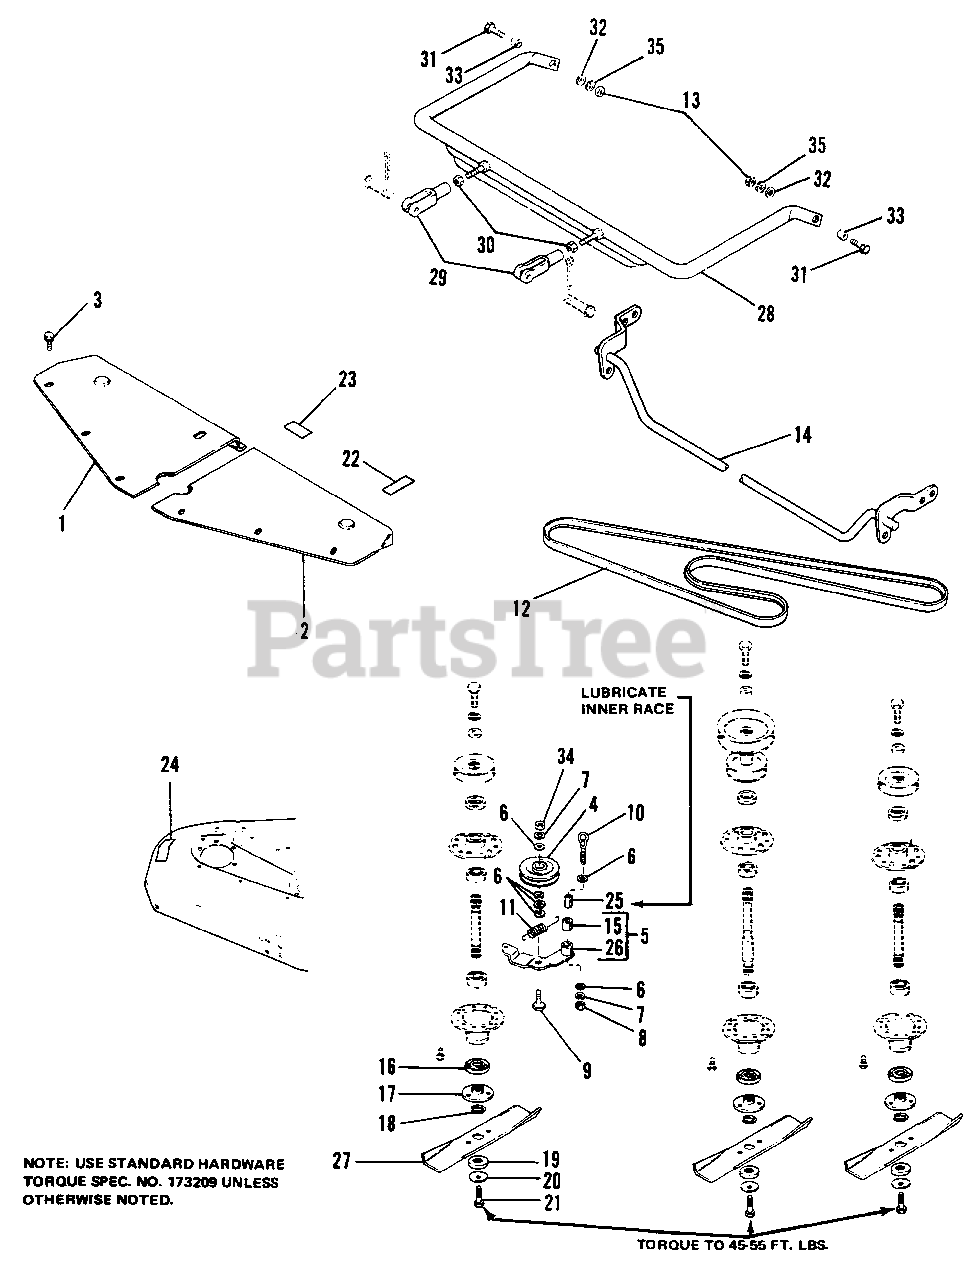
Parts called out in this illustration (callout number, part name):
1	COVER, R.H.
2	COVER, L.H.
3	SCREW, Hex, Taptite, 1/4-20 x 3/8
4	PULLEY, Idler
5	LEVER ASSY, Idler (w/Bushings)
6	WASHER, Plain, 5/16
7	LOCKWASHER, 3/8
8	NUT, Hex, Full, 3/8-16
9	CAPSCREW, Hex Hd., 3/8-16 x 1-1/4
12	BELT, V, Arbor Drive
13	NUT, Hex, Full, 1/2-13
14	ROCKER ARM ASSY
16	SHIELD, Grass
17	ADAPTOR, Blade
18	RING, Self Locking
19	WASHER, Spline
20	WASHER, Spline
21	CAPSCREW, Hex Hd., 7/16-14 x 1
22	DECAL, Danger
23	DECAL, Belt Installation
24	DECAL, Danger
25	RACE, Inner
26	LEVER ASSY, Idler
27	BLADE, 48" Mower
30	NUT, Hex, Jam. 1/2-20
31	CAPSCREW, Hex Hd., 1/2-13 x 1-1/4
32	WASHER, Plain, 7/16
34	NUT, Hex, Jam, 3/8-16
35	LOCKWASHER, 1/2
